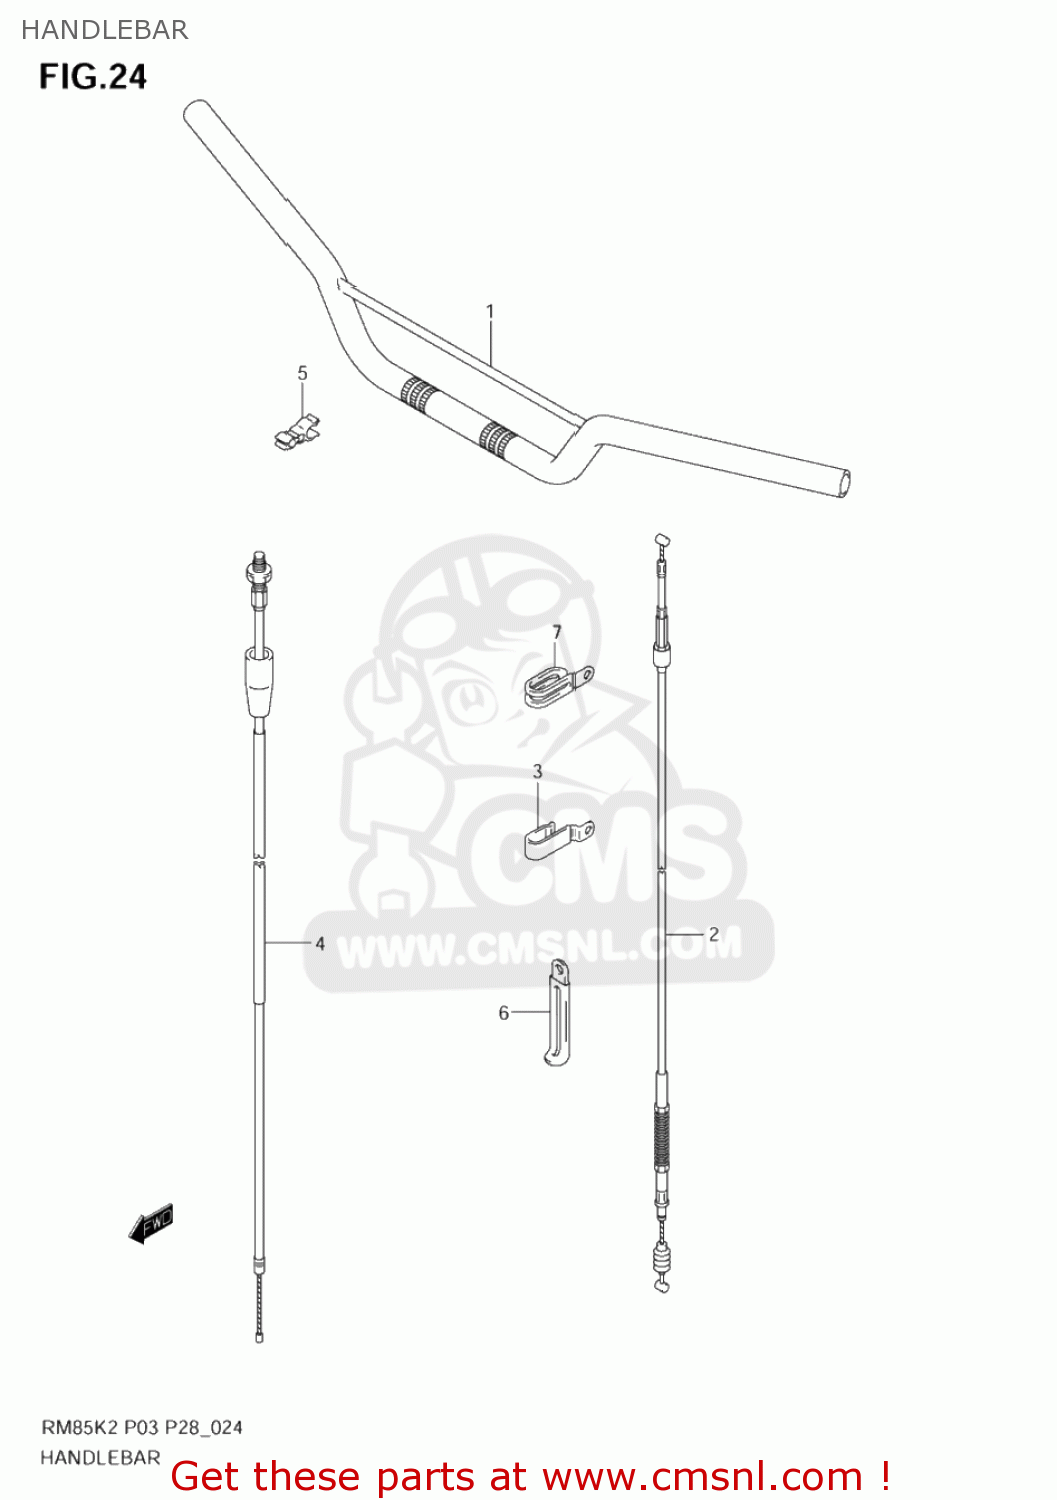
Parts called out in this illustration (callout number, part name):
1	HANDLEBAR COMP
2	CABLE ASSY,CLUTCH
3	CLAMP
4	CABLE ASSY,THROTTLE
5	CLAMP
6	CLAMP(L:65)
7	CLAMP
